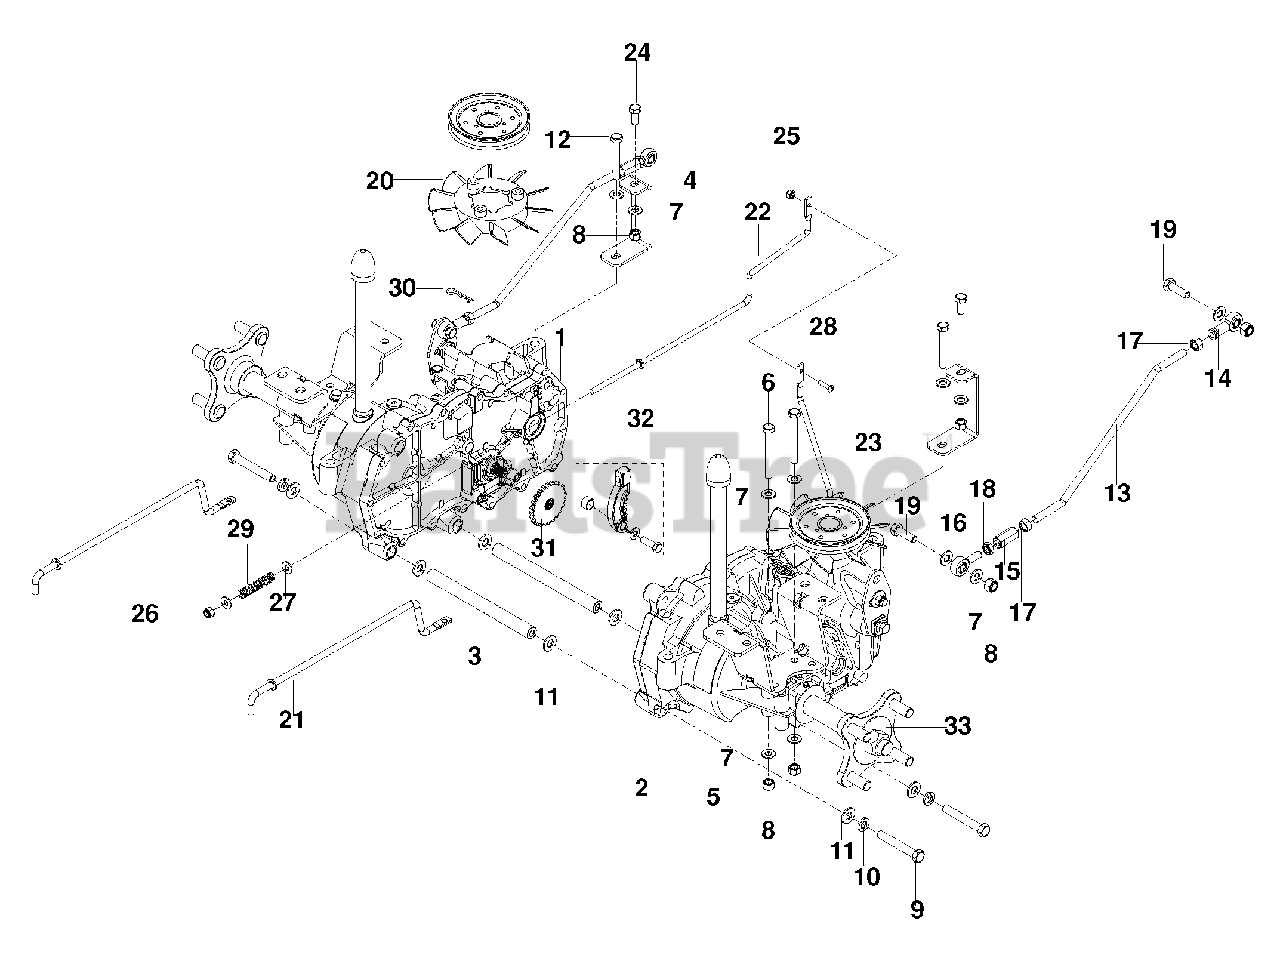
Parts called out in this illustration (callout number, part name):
3	SPACER TUBE
4	SUPPORT, EZT FRT
5	MOUNT, EZT RR
6	HCS 5/16-18 x 2 3/4
7	WASHER 5/16 SAE FLT
8	NUT 5/16-18 HEX NYLOC
9	HCS 3/8-16 x 2 1/2
10	WASHER 3/8 SPLT LK
11	WASHER 3/8 SAE FLT
12	HCS 5/16-18 x 2 1/4
13	ROD, MOTION CONTROL
14	ROD END RH
15	COUPLER, ROD END
16	ROD END MALE LH
17	NUT 5/16-24 HEX
18	NUT 5/16-24 HEX JAM LH
19	HCS 5/16-18 x 1
20	BLADE, FAN
21	LINK ARM, BYPASS
22	ROD, EZT BRAKE LT
23	ROD, EZT BRAKE RT
24	HCS 5/16-18 x 3/4
25	NUT 10-24 HEX NYLOC
26	NUT 1/4-20 HEX NYLOC
27	WASHER 1/4 FLT SAE
28	SCREW 10-24 x 3/4 SLTD RD
29	SPRING, BRAKE ROD
30	HAIRPIN, COTTER
31	COG, BRAKE DISC
32	BRAKE ARM KIT
